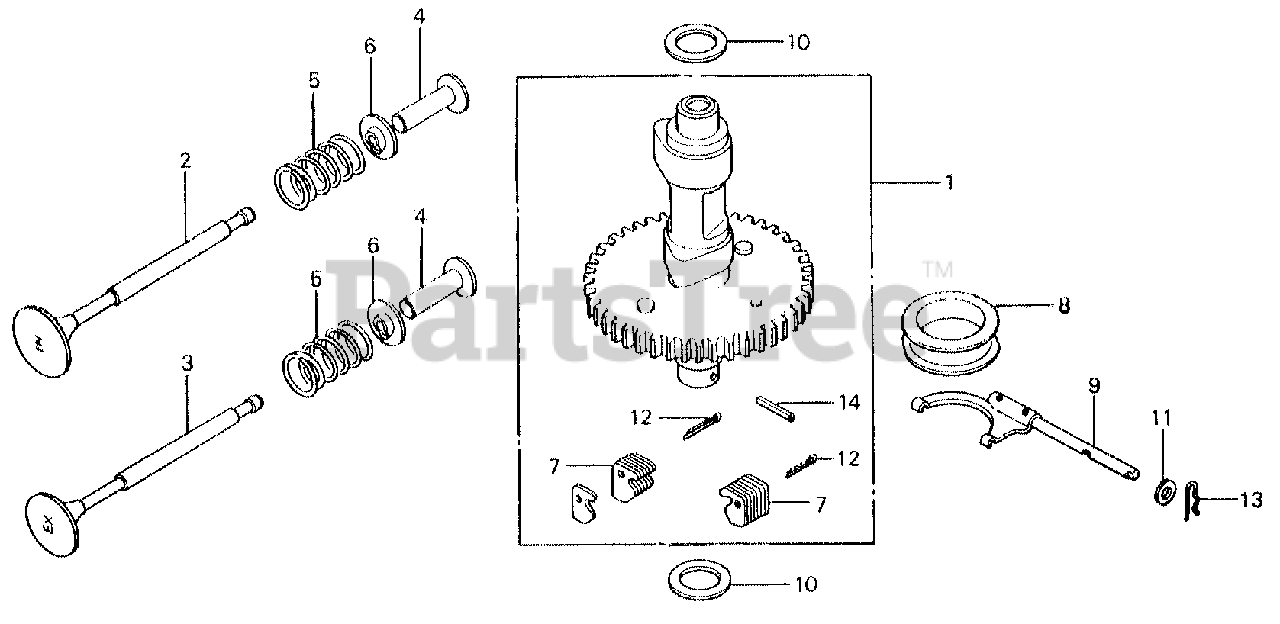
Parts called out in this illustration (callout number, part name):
1	CAMSHAFT ASSY.
2	VALVE, IN.
3	VALVE, EX.
4	LIFTER, VALVE (39.6MM)
4	LIFTER, VALVE (39.9MM)
5	SPRING, VALVE
6	RETAINER, VALVE SPRING
7	WEIGHT, GOVERNOR
8	SLIDER, GOVERNOR
9	SHAFT, GOVERNOR
10	WASHER, THRUST (18MM)
11	WASHER, PLAIN (6MM)
12	PIN, COTTER (3.0X45)
13	PIN, LOCK (8MM)
14	PIN, SPRING (2.5X16)
